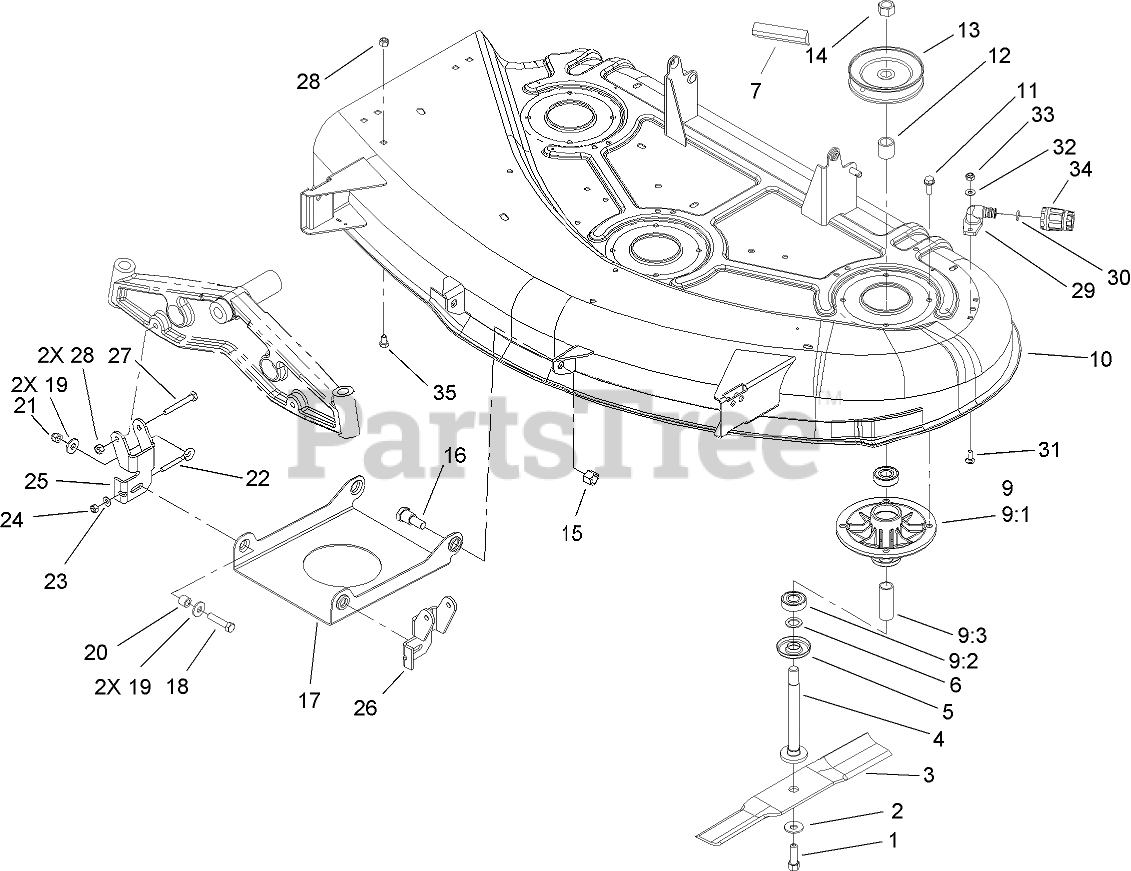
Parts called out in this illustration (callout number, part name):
1	SCREW-HH
2	WASHER-BELLEVILLE
3	Blade
4	SHAFT-SPINDLE
5	SHIELD-BEARING
6	SPACER
7	V-BELT, 44IN DECK
9	Spindle ASM
9:1	HOUSING-SPINDLE
9:2	BEARING-BALL
9:3	SPACER
10	DECK ASM
11	SCREW-TAPTITE
12	SPACER
13	PULLEY ASM
14	NUT-HEX
15	NUT-LOCK, NI
16	BOLT-SHOULDER, HH
17	PAN-DECK SUSPENSION, FRONT
18	SCREW-HH
19	WASHER-HARDENED
20	SPACER
21	NUT-LOCK, NI
22	SCREW-ADJUSTING
23	WASHER-FLAT
24	NUT-LOCK, NI
25	BRACKET-RH
26	BRACKET-LH
27	SCREW-HH
28	NUT-LOCK, NI
29	FITTING-WASHOUT
30	O-RING
31	BOLT-CARR
32	WASHER-FLAT
33	NUT-LOCK, NI
34	CONNECTOR-HOSE
35	SCREW-HH
